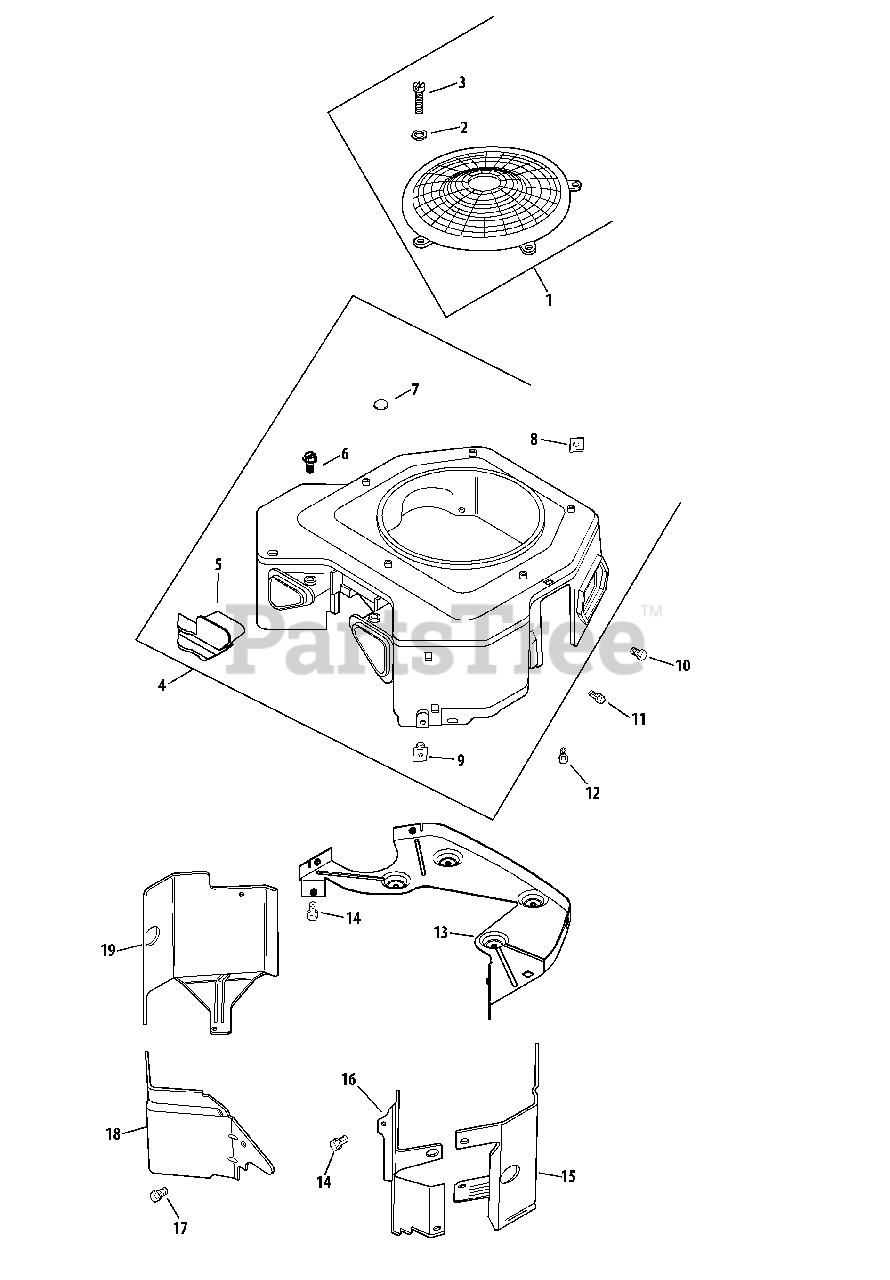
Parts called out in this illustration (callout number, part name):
1	Fixed Guard Kit
2	Flat Washer, 7/32
3	Pan Screw, M5 x 0.8 x 10
4	Blower Housing Kit
5	Blower Housing Cover
6	Washer Screw, #8-18 X 1/2
7	Button Plug, 9/16
10	Thread Forming Void Screw
11	Flange Screw, M5 x 0.8 x 16
12	Flange Screw, M5x.8X20
13	Backing Plate
14	Flange Screw, M6 x 1.0 x 16
16	Valley Baffle, #2
17	Flange Screw, M5 x .8 X 10
18	Valley Baffle, #1
